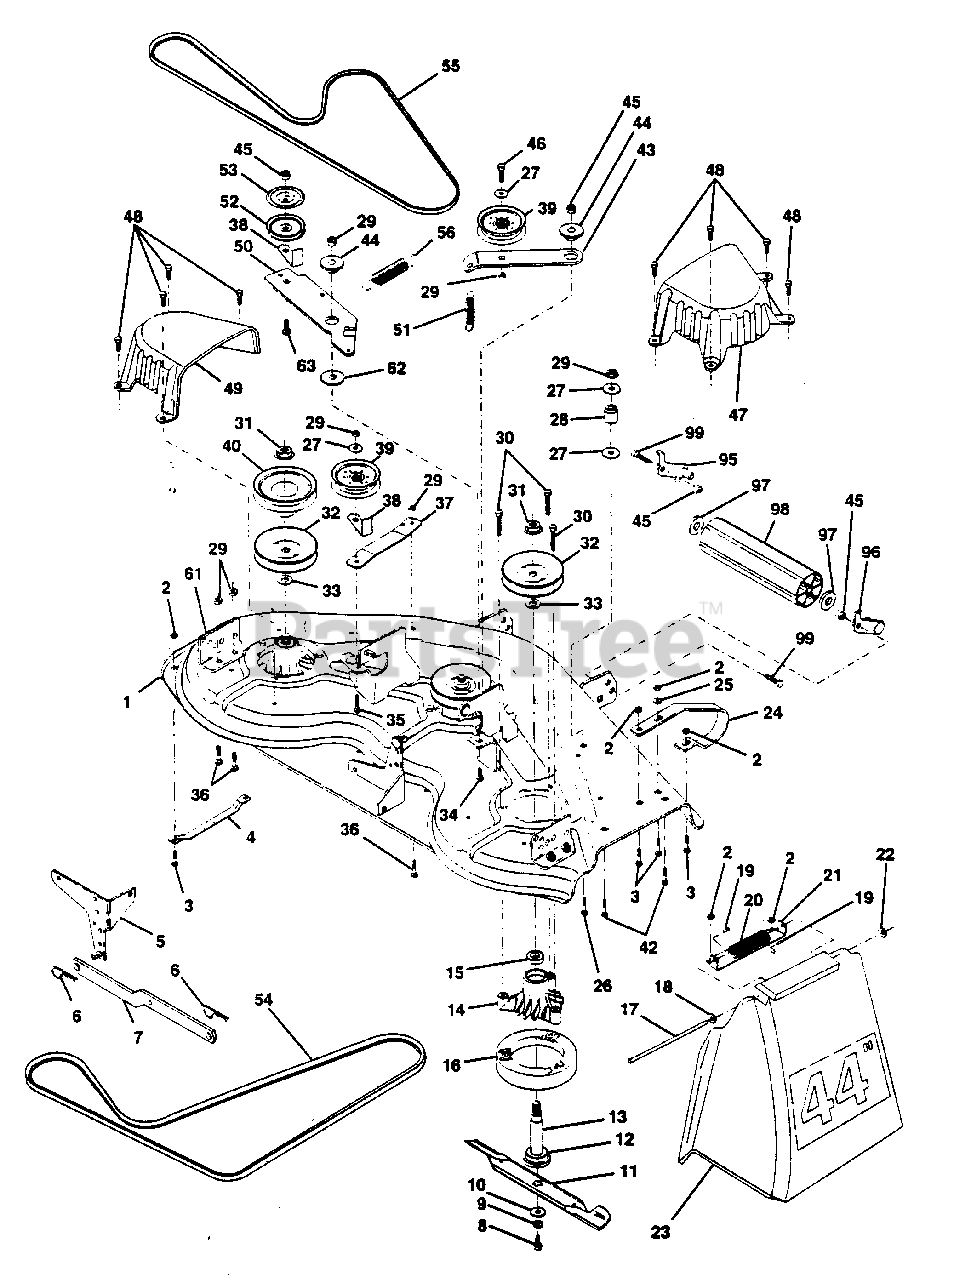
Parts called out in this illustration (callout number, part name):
1	Deck Asm., Mower 44" Vented
2	Locknut, Hex W/Ins 5/16-18 Unc
3	Bolt, Carriage 5/16-18 x 3/4
4	Runner, Mower LH
5	Bracket Asm., Sway Bar
6	Retainer, Spring
7	Arm Suspension, Rear
8	Bolt 3/8-24 x 1.25 Gr. 8 Patched
9	Washer, Lock Hvy 3/8 Unplated
10	Washer, Hard Blade Mower Vented
11	Blade (3 Required)
12	Bearing, Ball #6204 (Mandrel)
13	Shaft Asm., W/Lower Brg (Inc. 12)
14	Housing, Mandrel 44" Vent
15	Bearing, Ball Mandrel
16	Stripper, Mower Vented
18	Washer 11/32 x 5/8 x 16 Ga.
20	Spring, Torsion Deflector
21	Bracket, Deflector
23	Shield, Deflector Mower
25	Washer 11/32 x 3/4 x 16 Ga.
26	Bolt, Carriage 3/8-16 x 1-3/4 Gr. 5
27	Washer 13/32 x 13/16 x 16 Ga.
28	Spacer, Spring Stop Idler
29	Nut, Lock Hex W/Wsh 3/8-16 Unc
30	Screw Thdrol. Hex Hd Zinc Mower
31	Nut, Flg Top Lock Cntr 9/16
32	Pulley, Mandrel
33	Washer, Spacer Mower Vented
34	Bolt, Carriage 3/8-16 x 1-1/4
35	Bolt, Carriage 3/8-16 x 2
36	Bolt, Carriage 3/8-16 x 1 Gr. 5
37	Stiffener, Arm Idler
38	Keeper, Belt Idler
39	Pulley, Idler Flat
40	Pulley, Driven
42	Bolt, Carriage 5/16-18 Unc x 3/4
43	Arm, Idler Secondary
44	Spacer, Retainer
45	Nut, Crownlock 3/8-16 Unc
46	Bolt, Fin Hex 3/8-16 Unc x 1-3/4
47	Cover, Mandrel RH
48	Screw, Thd Roll 1/4-20 x 5/8
49	Cover, Mandrel LH
50	Arm, Idler Primary
51	Spring, Secondary
52	Pulley, Idler V Groove
53	Shield, Idler
54	V-Belt, Mower Primary
55	V-Belt, Mower Secondary
56	Spring, Primary
61	Bracket, Gauge Wheel
62	Washer Hardened
63	Bolt Carriage 3/8-16 x 1-1/2
95	Bracket, Nose Roller L.H.
96	Bracket, Nose Roller R.H.
97	Washer, 17/32 x 7/8 x 16Ga.
99	Bolt, Hex 3/8-16 x 1
